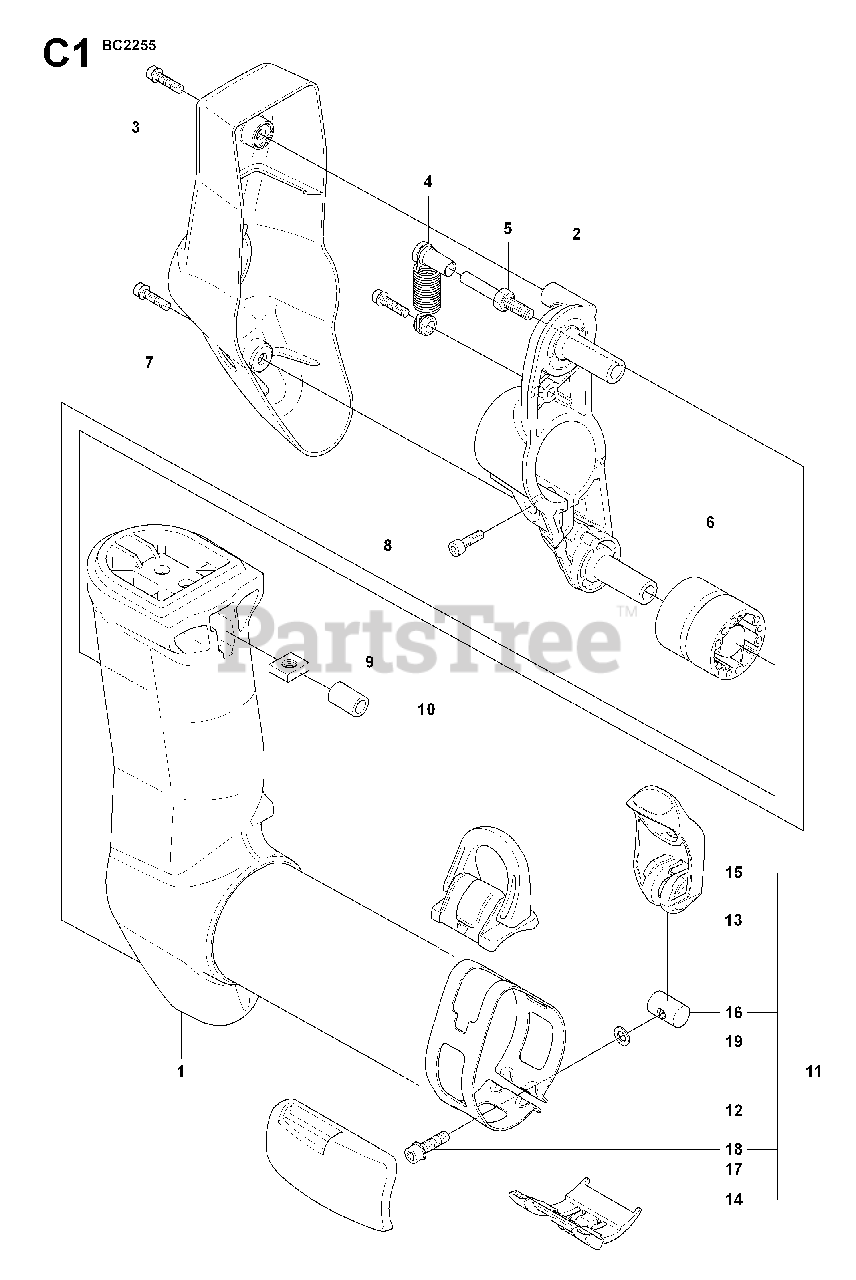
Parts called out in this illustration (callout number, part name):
4	SPRING
5	PARALLEL PIN
6	ANTIVIBE ELEMENT
7	SCREW IHSCFM
19	WASHER 5.3X12
